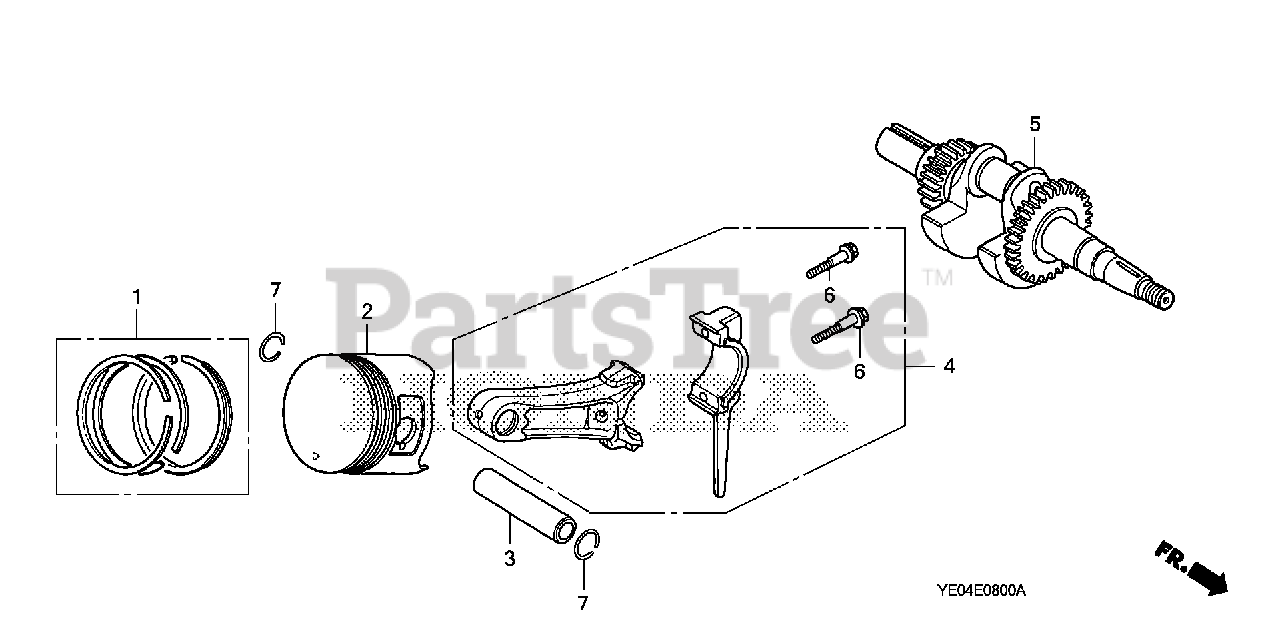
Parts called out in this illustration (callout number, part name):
1	RING SET, PISTON (STD) (TPR)
1	RING SET, PISTON (STD) (RIKEN)
1	RING SET, PISTON (0.75) (TPR)
1	RING SET, PISTON (0.75) (RIKEN)
1	RING SET, PISTON (0.25) (TPR)
1	RING SET, PISTON (0.25) (RIKEN)
1	RING SET, PISTON (0.50) (TPR)
1	RING SET, PISTON (0.50) (RIKEN)
2	PISTON (STD)
2	PISTON (0.25)
2	PISTON (0.50)
2	PISTON (0.75)
3	PIN, PISTON
4	ROD ASSY., CONNECTING (TH)
5	CRANKSHAFT
6	BOLT, CONNECTING ROD
7	CLIP, PISTON PIN (18MM)
